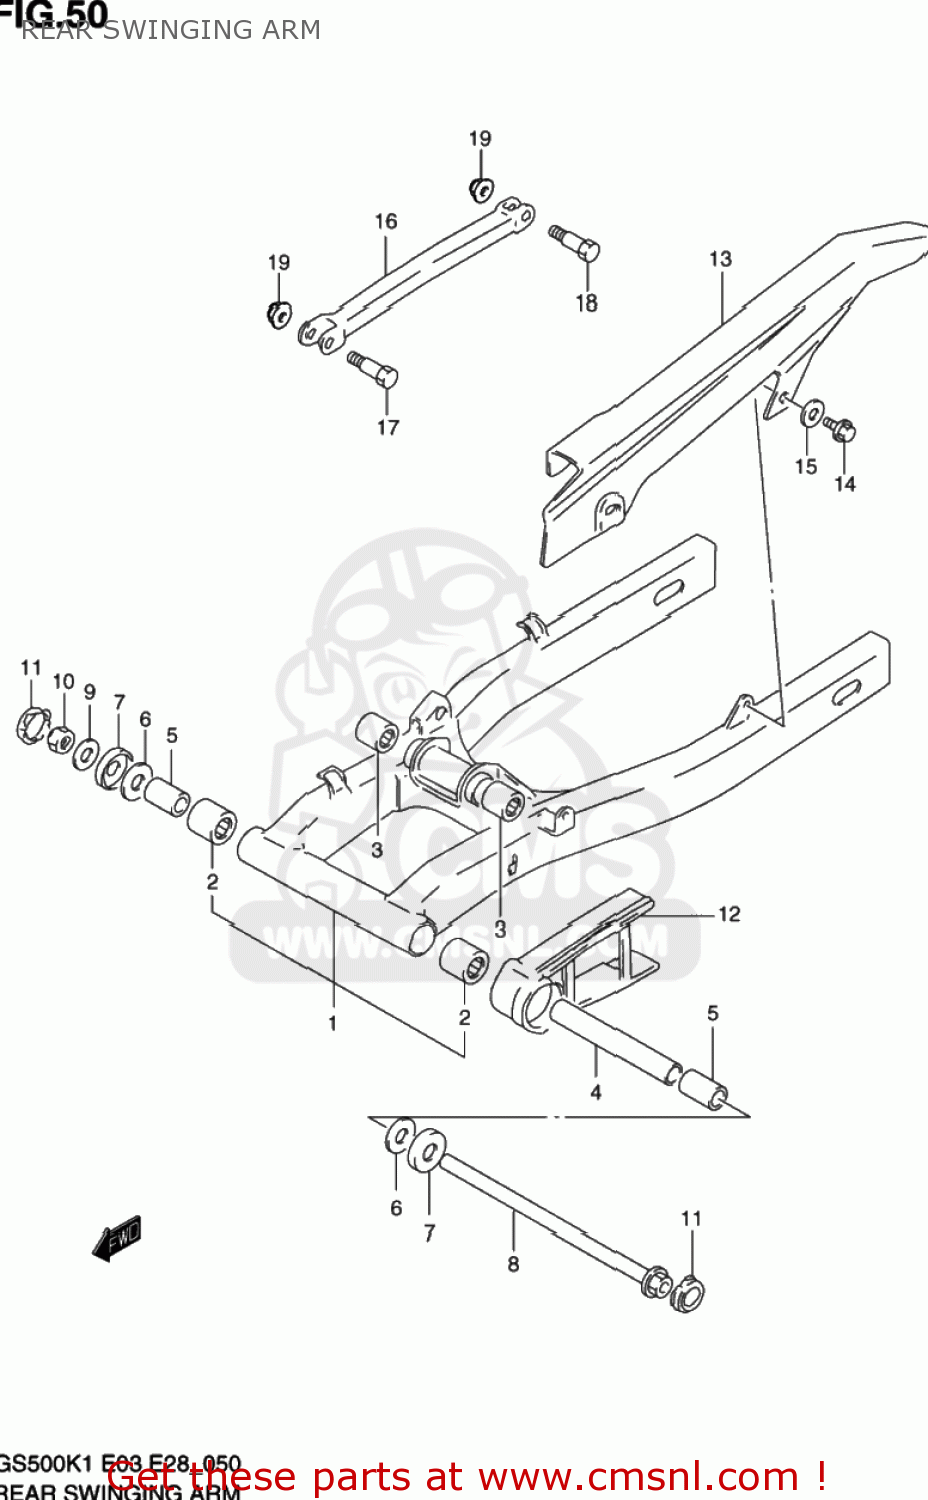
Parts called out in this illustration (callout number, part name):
1	SWINGINGARM ASSY,RR
2	BEARING(22X29X30)
3	BEARING(17X24X25)
4	SPACER,RR SWGARM PIVOT CTR
5	SPACER,RR SWGARM PIVOT
6	WASHER(14.2X34X1)
7	CVR,RR SWGARM DUST SEAL(OD:40)
8	SHAFT,RR SWINGINGARM PIVOT
9	WASHER(14.5X29X2.3)
10	NUT
11	CAP,RR SWINGING ARM PIVOT
12	BUFFER,CHAIN TOUCH DEFENSE
13	CASE,CHAIN
14	SCREW 6X12
15	WASHER
16	TORQUELINK,RR
17	BOLT(10X41)
18	BOLT(10X34)
19	NUT
